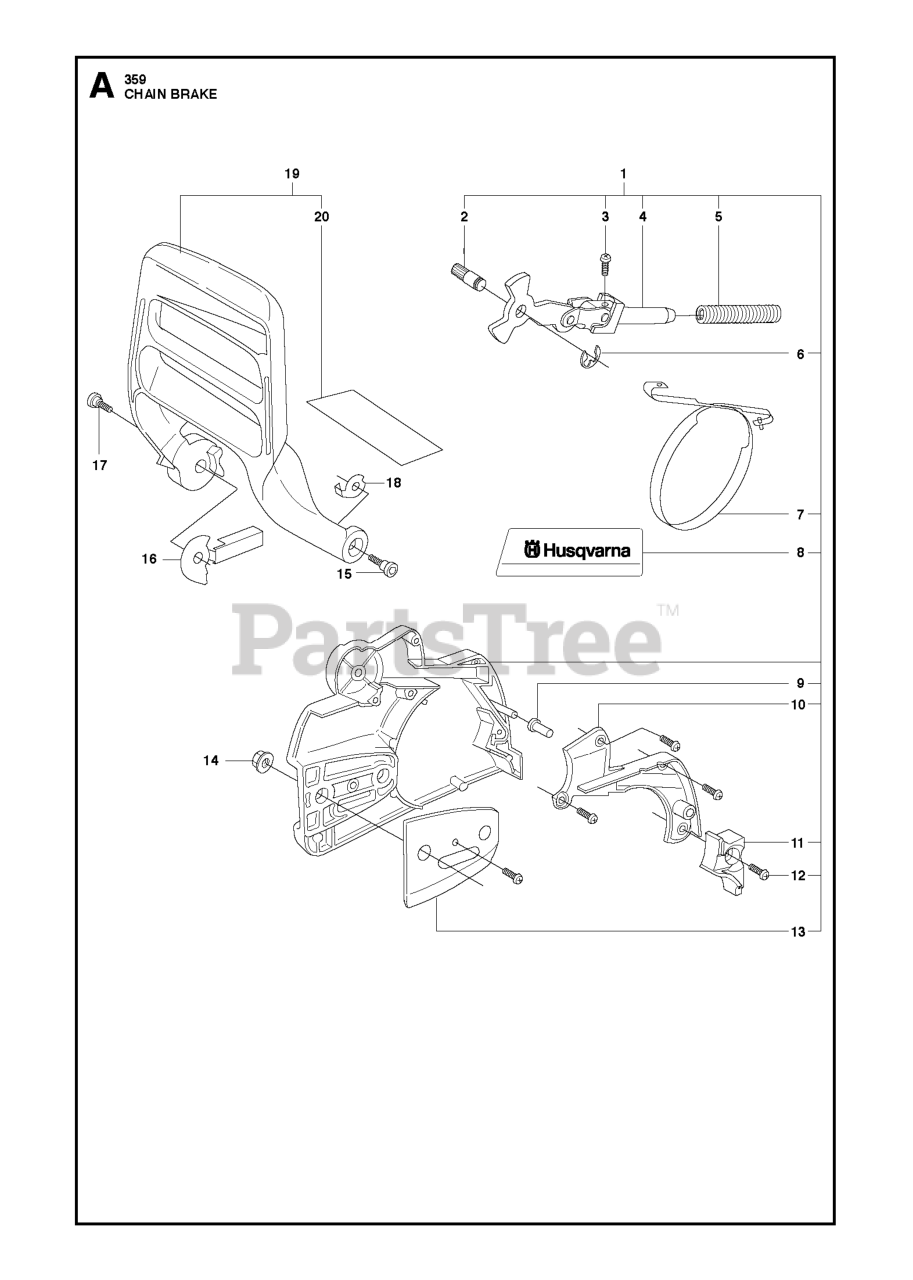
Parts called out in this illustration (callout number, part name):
1	CHAIN BRAKE
7	BRAKE BAND
14	NUT M8 FLANGE
20	PROTECTOR
